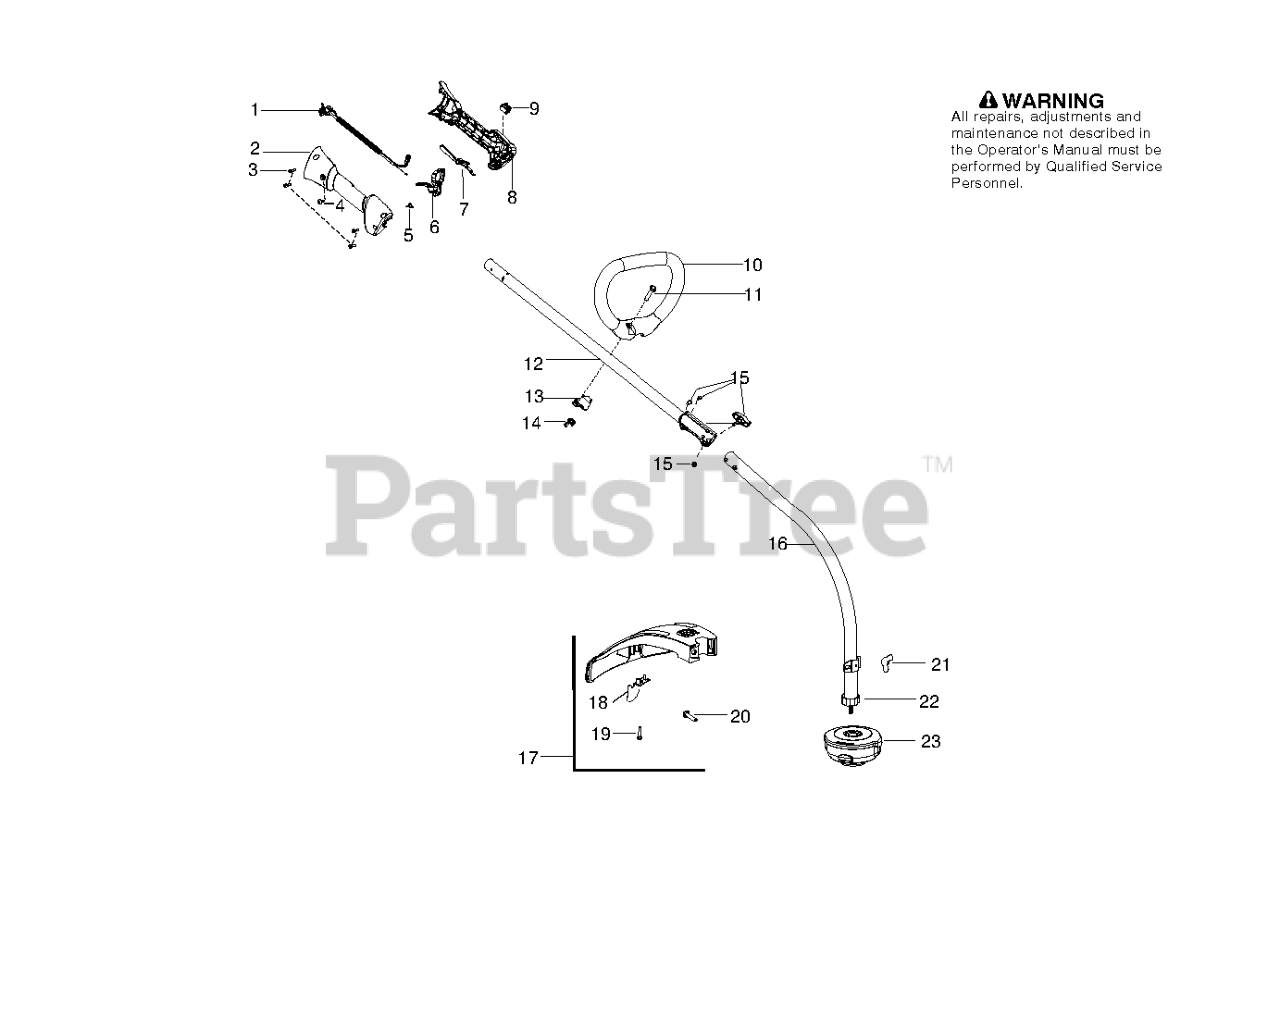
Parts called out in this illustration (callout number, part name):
1	ASSY CABLE / WIRE HARNESS
2	HSG THROTTLE RIGHT HVA
3	SCREW M4 X 1.75 PT 16MM
4	SCREW-10-14 X 1/2 PLASTITE
5	SPRING TRIGGER
6	TRIGGER THROTTLE HVA ORANGE
7	THROTTLE LOCKOUT HVA ORANGE
8	HSG THROTTLE LEFT HVA
9	SWITCH
11	BOLT, TYPE 2
12	KIT UPPER SHAFT SILVER
13	CLAMP ASSIST HANDLE
14	WINGNUT, TYPE 2
15	ASSY COUPLER BLACK
16	KIT DRIVESHAFT
17	TRIMMER GUARD 128C
20	BOLT, TYPE 2
21	WINGNUT, TYPE 2
22	DUST CUP
23	T25 TRIM HEAD RH
